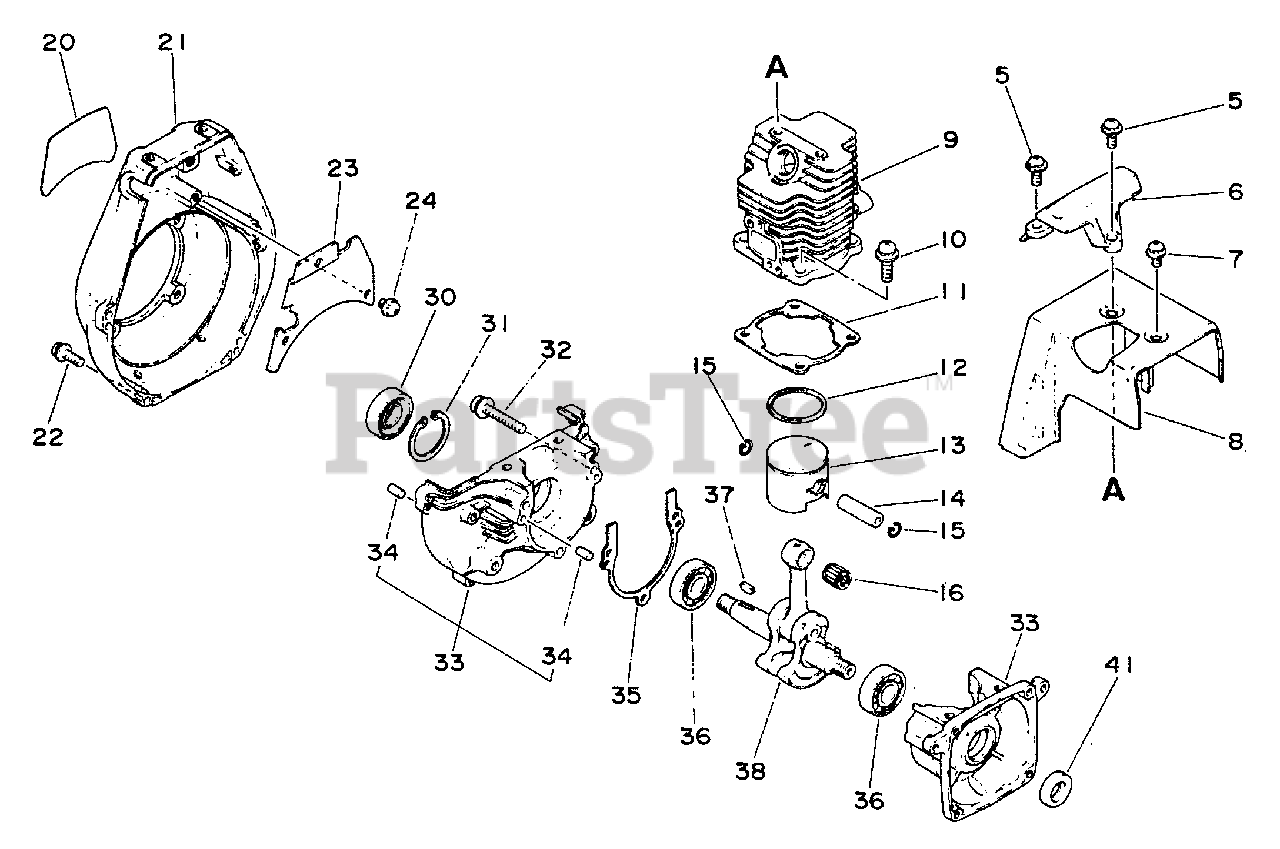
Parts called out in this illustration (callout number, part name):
5	SCREW - 4X14
6	GUARD - TOP
7	SCREW - 4X10
8	COVER, ENGINE
9	CYLINDER
10	SCREW - 5X16
11	GASKET, CYLINDER
12	RING, PISTON
13	PISTON
14	PIN, PISTON
15	RING, RETAINING
16	BEARING, NEEDLE
20	LABEL - MODEL
21	COVER, FAN
22	SCREW - 4X16
23	SHIELD, FAN
24	SCREW - 4X8
30	SEAL, OIL - 12
31	RING, RETAINING - 28
32	SCREW - 5X28
33	CRANKCASE KIT
34	PIN - LOCATING
35	GASKET, CRANKCASE
36	BEARING, BALL - 6001C3
38	CRANKSHAFT ASSY
41	SEAL, OIL
